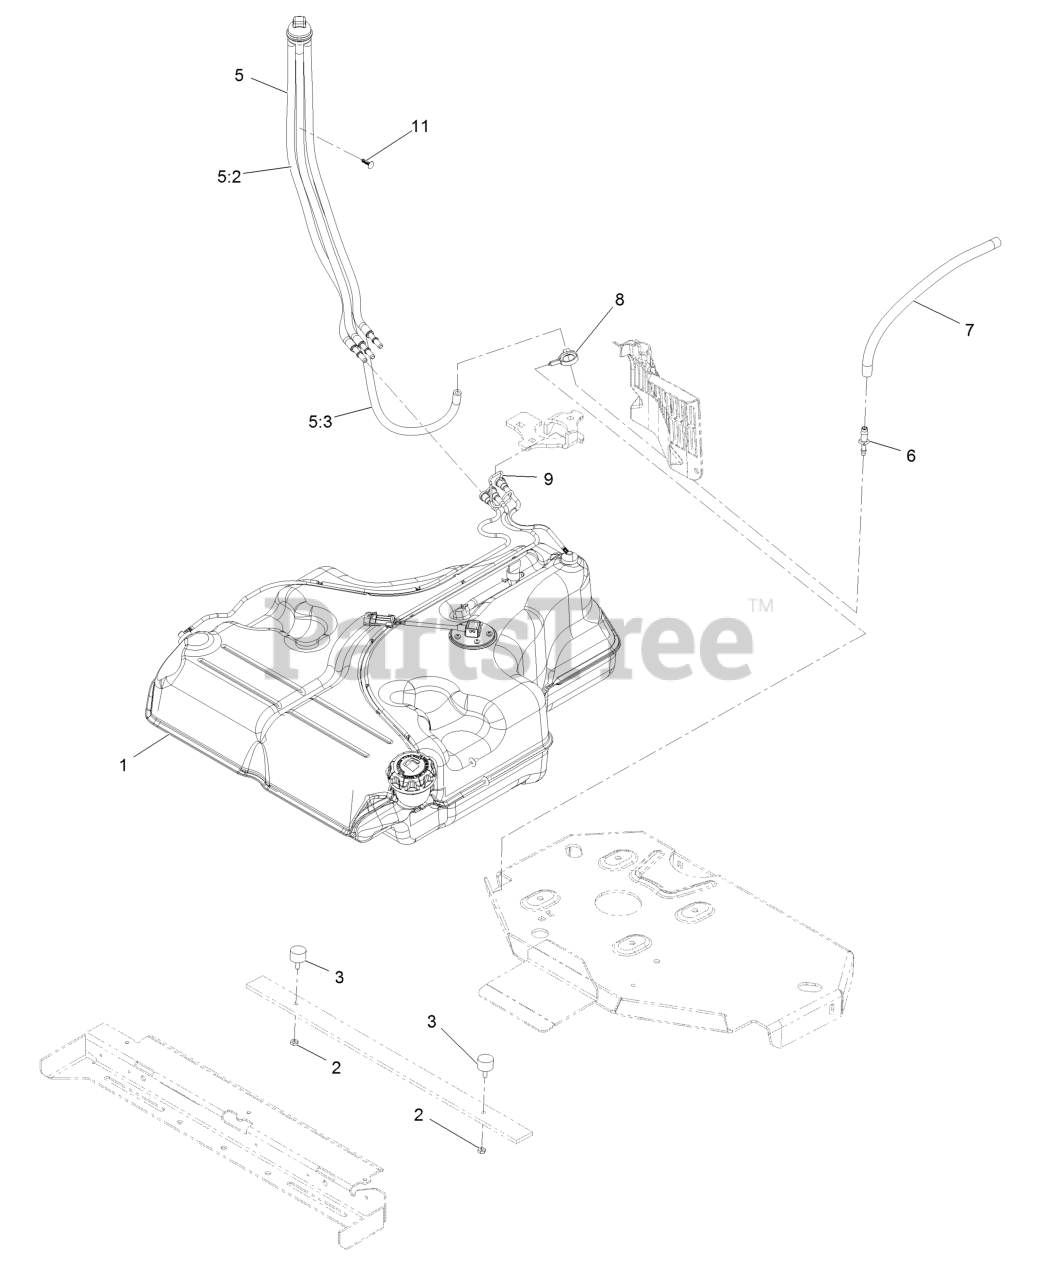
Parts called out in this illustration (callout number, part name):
1	Fuel Tank ASM
2	Nut-Jam
5	Fuel Manifold Vent ASM
5:2	Hose-Fuel
5:3	Hose-Fuel
6	Fitting-Straight
7	Hose-Fuel
8	Clamp-Hose
9	Retainer-Line, Vapor
11	Plug-Plastic
